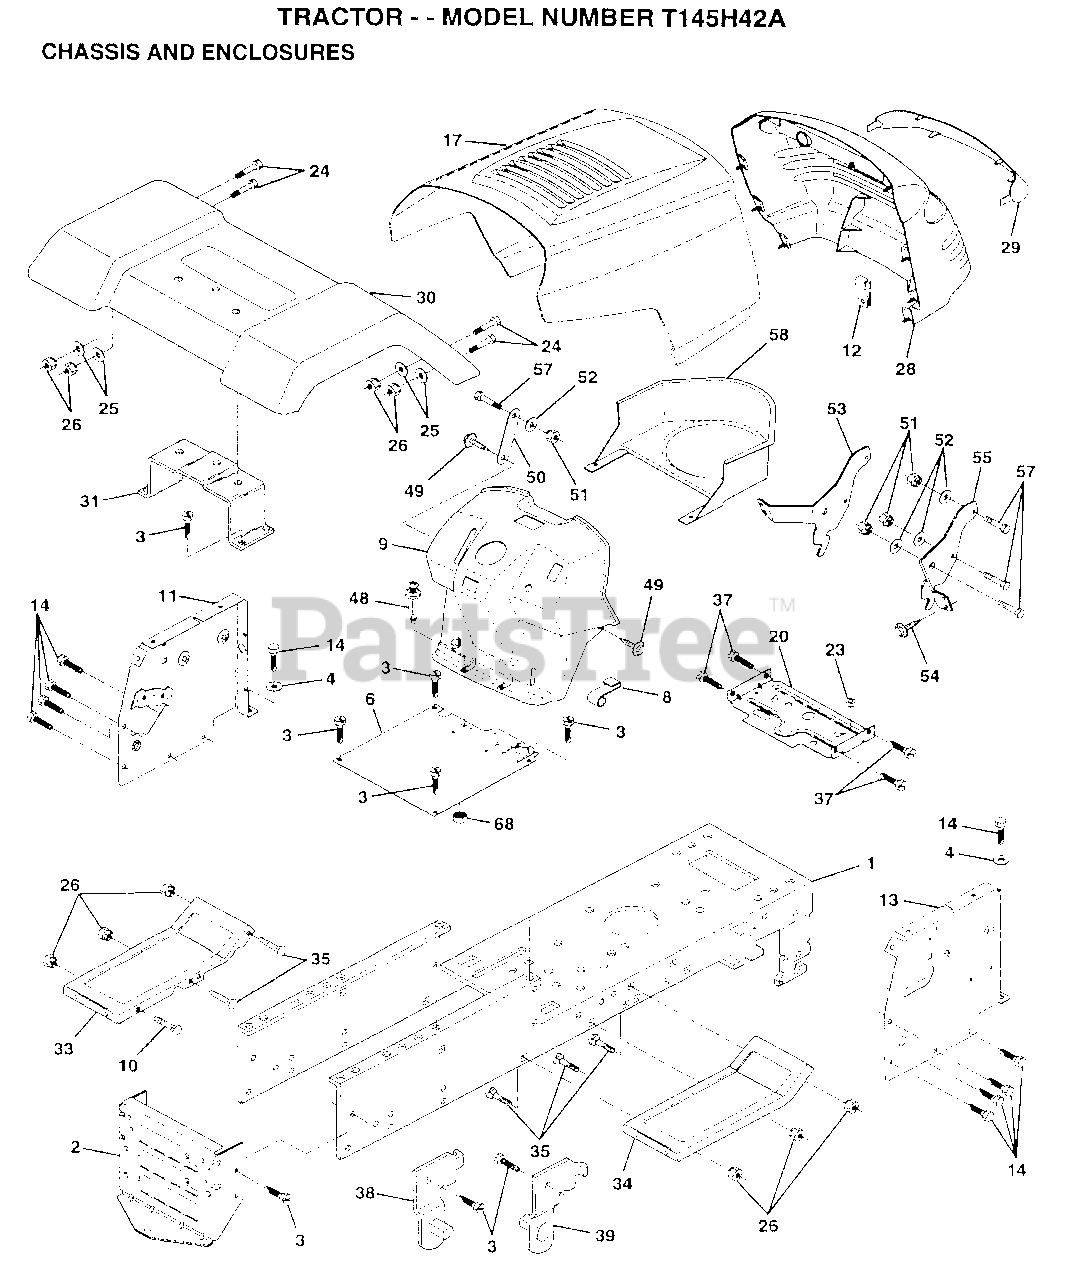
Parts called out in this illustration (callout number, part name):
1	CHASSIS.WLD.11GA
3	SCREW
4	WASHER
5	CLIP.TINNERMAN
8	"CLIP,INSULATOR"
11	PANEL.DASH.LH.
13	PANEL.DASH.RH
14	SCREW LT
20	PLATE.MTG.BTRY.TK
24	BOLT
25	WASHER
26	NUT
29	LENS GRILLE
31	BRKT FENDER
33	FOOTREST.LH.LT/GT
34	FOOTREST.RH.LT/GT
35	BOLT
37	SCREW
38	BRACKET ASM LH
39	BRACKET ASM RH
48	RIVET.PUSH.PLATE
49	SCREW HEX CRT
50	BRACE SUPT DASH
51	NUT
52	WASHER
53	BRACKET.GRILLE.LH
55	BRACKET.GRILLE.RH
58	DUCT AIR 12-15H
68	NUT
